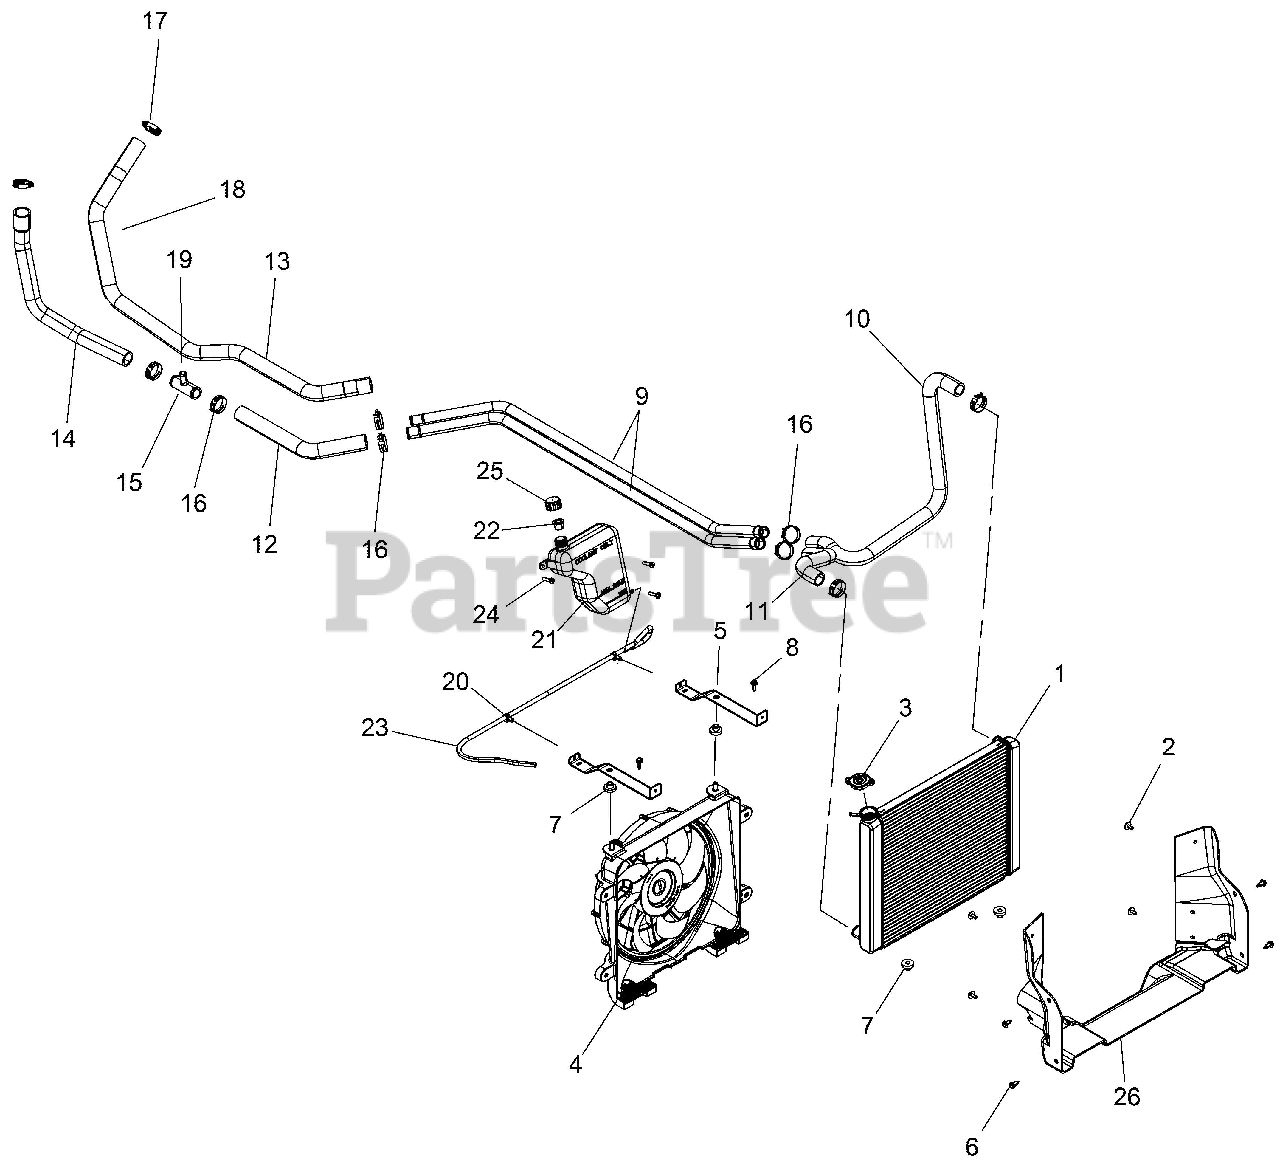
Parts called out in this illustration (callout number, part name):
1	ASM-RADIATOR, CORE
2	BOLT-M6X15MM
4	FAN-ASSEMBLY
5	MOUNT, RADIATOR, BLACK
6	RIVET-TUFLOCK, .315-.325 X .787
8	SCR-M6 X 1.0 X 20, HXHD, FLG, TDFM, BL
9	TUBE-COOLANT, 1"
10	HOSE-UPPER, RAD
11	HOSE-LOWER, RAD
12	HOSE, ENGINE, IN
13	HOSE, ENGINE, OUT
14	HOSE, ENGINE, BYPASS
15	CONNECTOR-TEE, 1 X 1 X 0.5
16	CLAMP, SPRINGBAND 35/12, BLK
17	CLAMP-HOSE(WORM DR) 25-40MM
18	CLIP-ROUTING
19	CLAMP-HOSE, SPRING, 20MM
21	TANK-SURGE
22	CAP, PLUG 9X(GRN), FLEX TEMP (10)
23	FUEL LINE-95 CENTIMETERS
24	SCR-#14 X 1 HI/LO-PH-PN-TRX-M
25	CAP, OVERFLOW
26	RADIATOR
